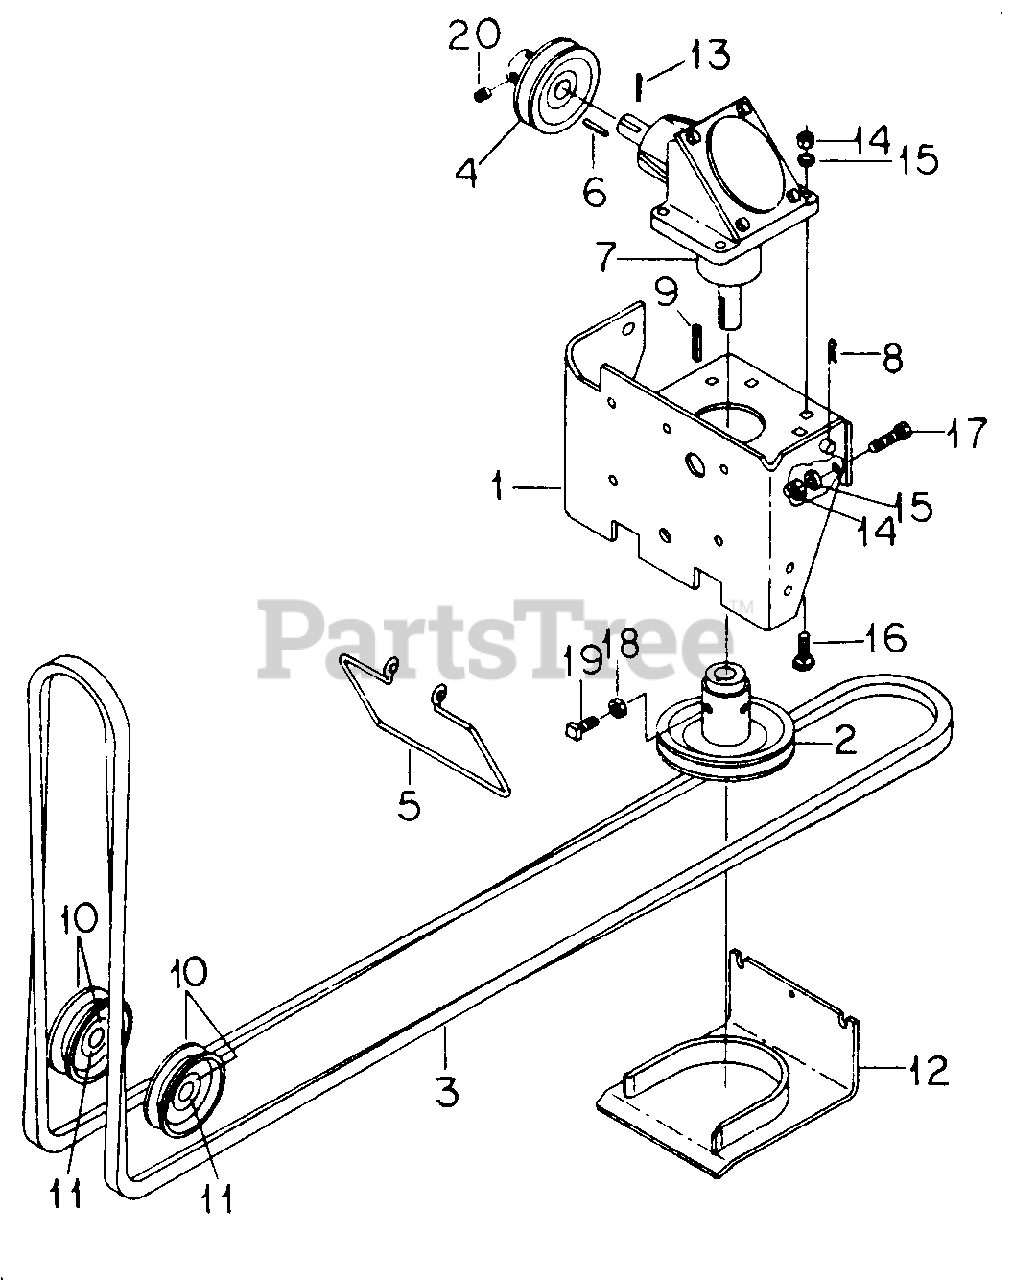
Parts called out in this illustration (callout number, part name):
1	Mounting Assy, Gear Box
2	Pulley w/Set Screws -2 Tiller
3	Belt, PTO Drive -2 Tiller
4	Pulley w/Set Screws
5	Guide, Belt -Hydro Transmission- -For No. 2 Tiller only
6	Key, 3/16 X 1-1/4 Sq Parallel
7	Box Assy Gear -90 Degree-
8	Pin, Quick Attachable Cotter
9	Key, 3/16 X 2 Sq Parallel
10	Pulley, Drive Belt Idler
11	Bearing Assy, Idler Pulley
12	Guard, Drive Belt -2B Tiller
13	Pin, 5/32 X 1-1/4 Cot
14	Nut, 3/8 Type 5
15	Washer, 3/8 Lock
16	Bolt, 3/8 X 1-1/4 Crg Type 5
17	Screw, 3/8-16 X 1 Lock
18	Nut, 5/16 Jam Type 5
19	Screw, 5/16 X 1 Znp Sq/Hd C/Pt Set
20	Screw, 5/16 X 3/8 Pln C/Pt Hdl/Hs Set
